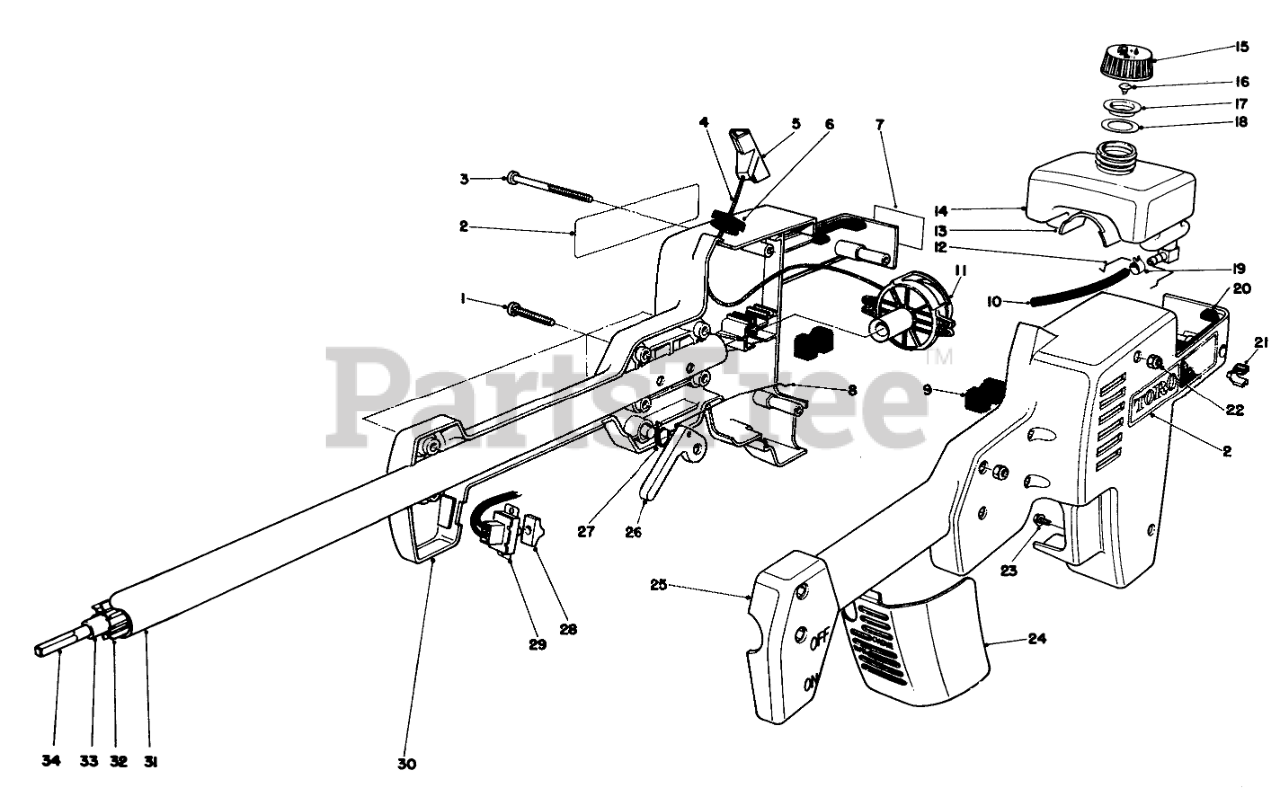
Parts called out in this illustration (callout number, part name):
1	Screw-Machine Cross Recess Pan Hd.
2	Decal-TC 650
3	Screw-Machine Cross Recess Pan Hd.
4	Rope-Starter
5	Handle
6	Bushing Rope
7	Decal-Hot
8	Link-Throttle
9	Isolation Mount
10	Gas Line
11	Recoil Assembly (Incl. Ref. #4-6)
12	Clip-Crankcase Pad
13	Crankcase Pad
14	GAS TANK
15	Gas Cap Assembly (Incl. Ref. #16-18)
16	Valve
17	Insert
18	Gasket
19	CLAMP-HOSE
20	Bumper-Gas Tank
21	Grommet
22	NUT-LOCK, NI
23	10-16 X 3/8 THDG SCREW
24	Cover-Air Cleaner
25	Housing Engine L.H.
26	Lever Throttle
27	TORSION SPRING
28	SWITCH COVER-BLACK
29	SWITCH
30	Housing-Engine R.H. (Incl. Ref. #7)
31	Tube-Upper
32	Spacer-Shaft
33	Casing-Shaft
34	Flexshaft
